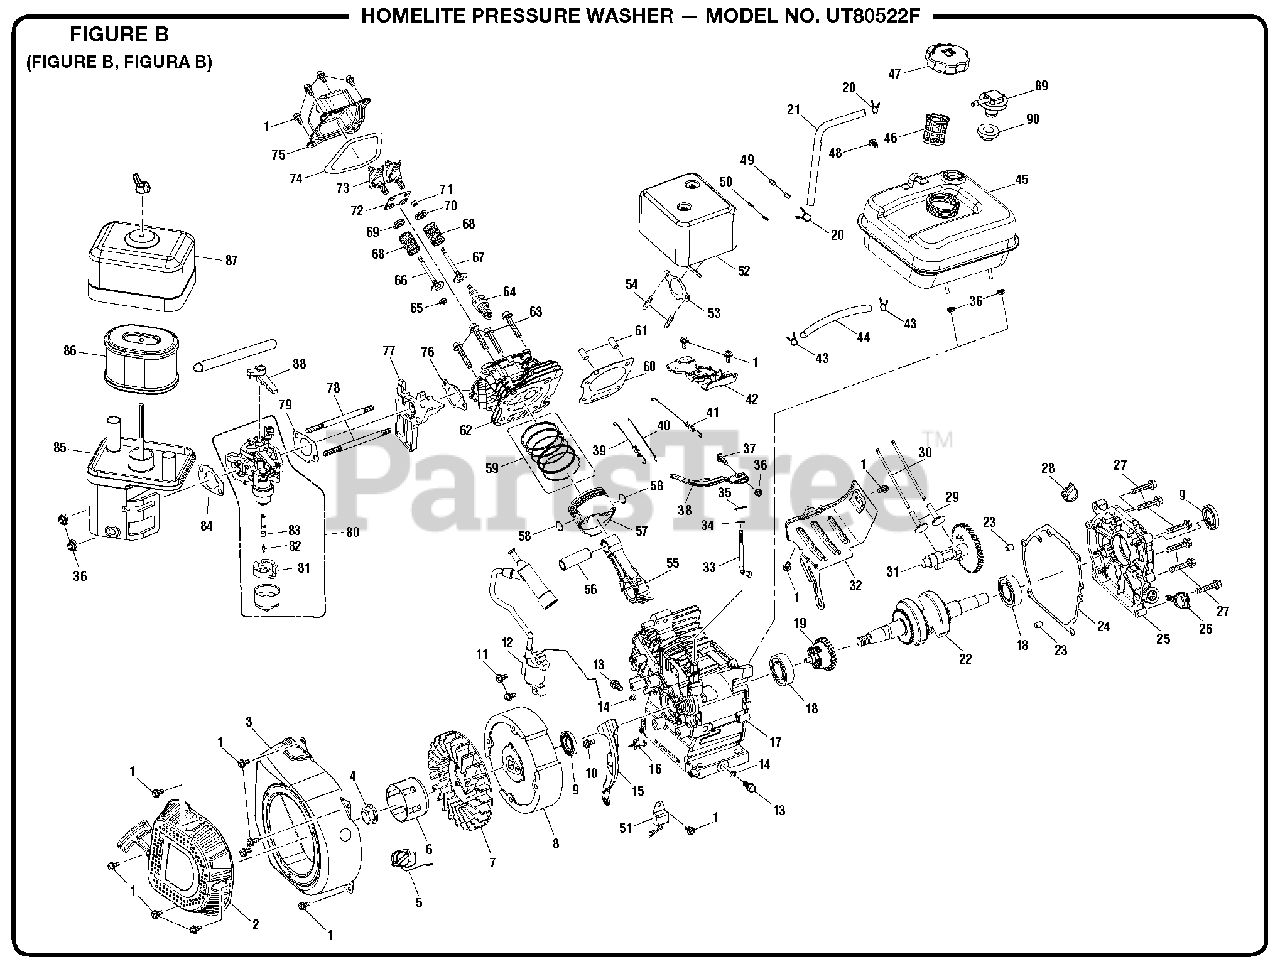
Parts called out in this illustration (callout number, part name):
1	Bolt
2	Recoil Starter Assembly
5	Switch Assembly
6	Starter Pulley
8	Flywheel Assembly
11	Bolt
12	Ignition Coil Assembly
13	Drain Plug Bolt
17	Crankcase Assembly
18	Ball Bearing
19	Governor Gear Assembly
20	Fuel Line Clip
22	Crankshaft Assembly
23	Pin
24	Crankcase Gasket
25	Crankcase Cover Assembly
26	Dipstick
31	Camshaft Assembly
36	Hex Nut
38	Governor Support Assembly
39	Throttle Valve Return Spring
41	Governor Spring
42	Upper Shroud Assembly
43	Fuel Line Clip
45	Fuel Tank Assembly
46	Fuel Filter
47	Fuel Cap
49	Hex Nut
50	Spring Washer
51	Oil Sensor
52	Muffler Assembly
53	Exhaust Outlet Gasket
55	Connecting Rod Assembly
58	Piston Pin Clip
60	Cylinder Head Gasket
61	Dowel Pin
62	Cylinder Head
67	Exhaust Valve
69	Valve Spring Seat
70	Exhaust Valve Retainer
71	Valve Rotator
72	Guide Plate Assembly
73	Rocker Assembly
74	Cylinder Head Gasket
75	Cylinder Head Cover Assembly
76	Carburetor Insulator Gasket
77	Carburetor Insulator Plate
79	Carburetor Gasket
80	Carburetor Assembly
84	Air Cleaner Gasket
85	Air Cleaner Base
86	Air Cleaner Element
87	Air Cleaner Case Cover
89	Rollover Valve
